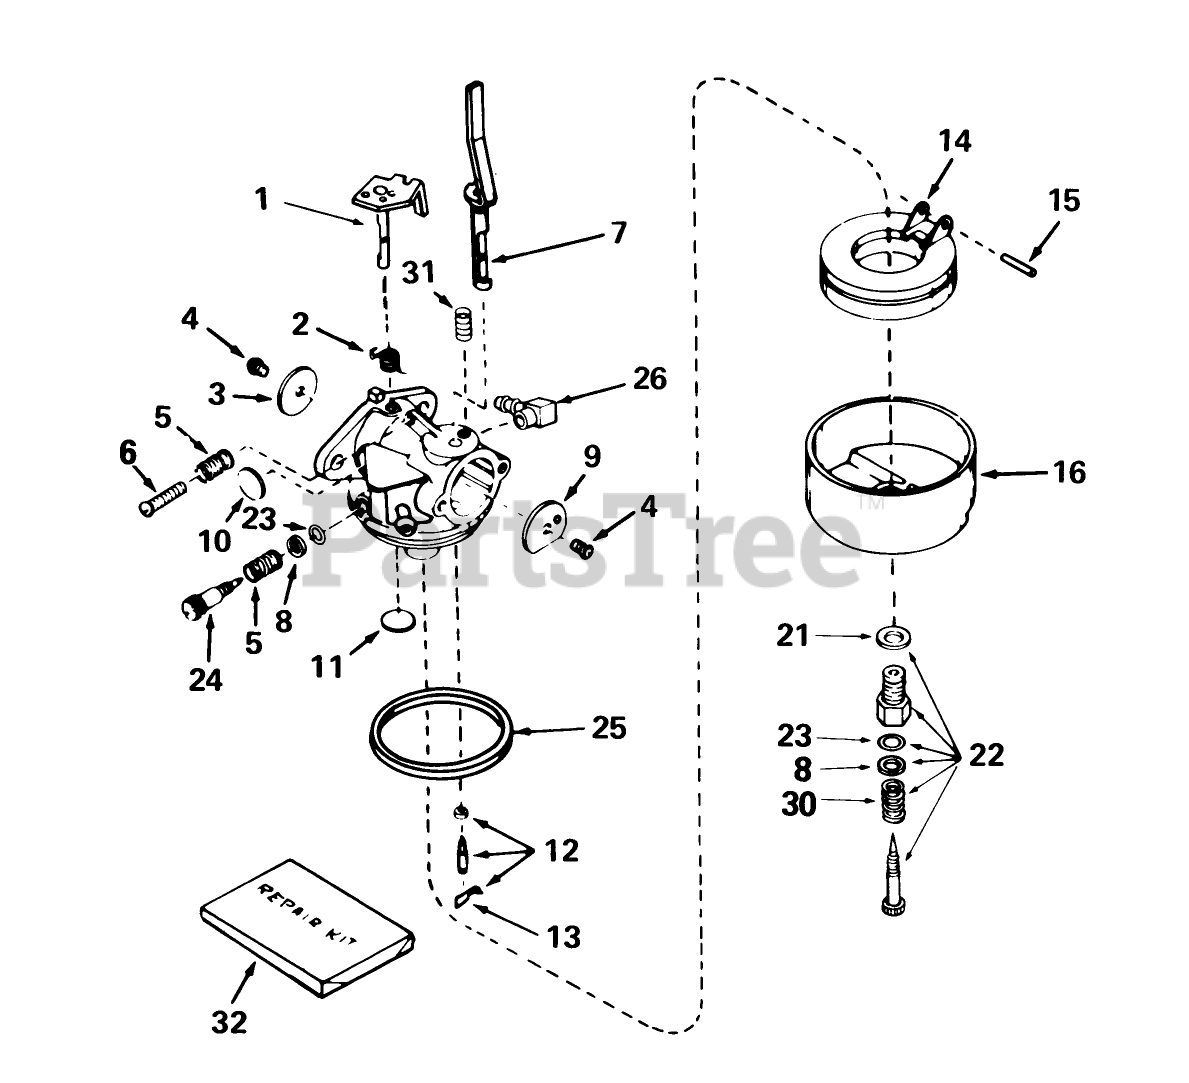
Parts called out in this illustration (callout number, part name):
1	Throttle Shaft and Lever ASM
2	Spring, Return
3	Shutter-Throttle
4	Screw-Shutter
5	Spring-Tension
6	Screw-Throttle Crack Screw / Idle Speed
7	Shaft Lever Assy., Choke
8	Washer
10	Plug-Welch, Idle Mixture Well
11	Plug-Welch, Atmospheric Vent
12	Inlet Needle, Seat Clip Assy. (Incl. No. 13)
13	Clip-Spring
14	Float
15	Shaft-Float
16	Bowl-Float (no drain)
21	Washer-Bowl Nut
22	Adjustment Screw Assy., Main (Incl. Nos. 5A, 21 23)
23	ORing
24	Screw, Idle Adj.
25	O Ring-Bowl, Float
26	Fitting-Fuel
30	Spring
31	Spring-Positioning, Choke
32	Repair Kit (Incl. items marked *)
